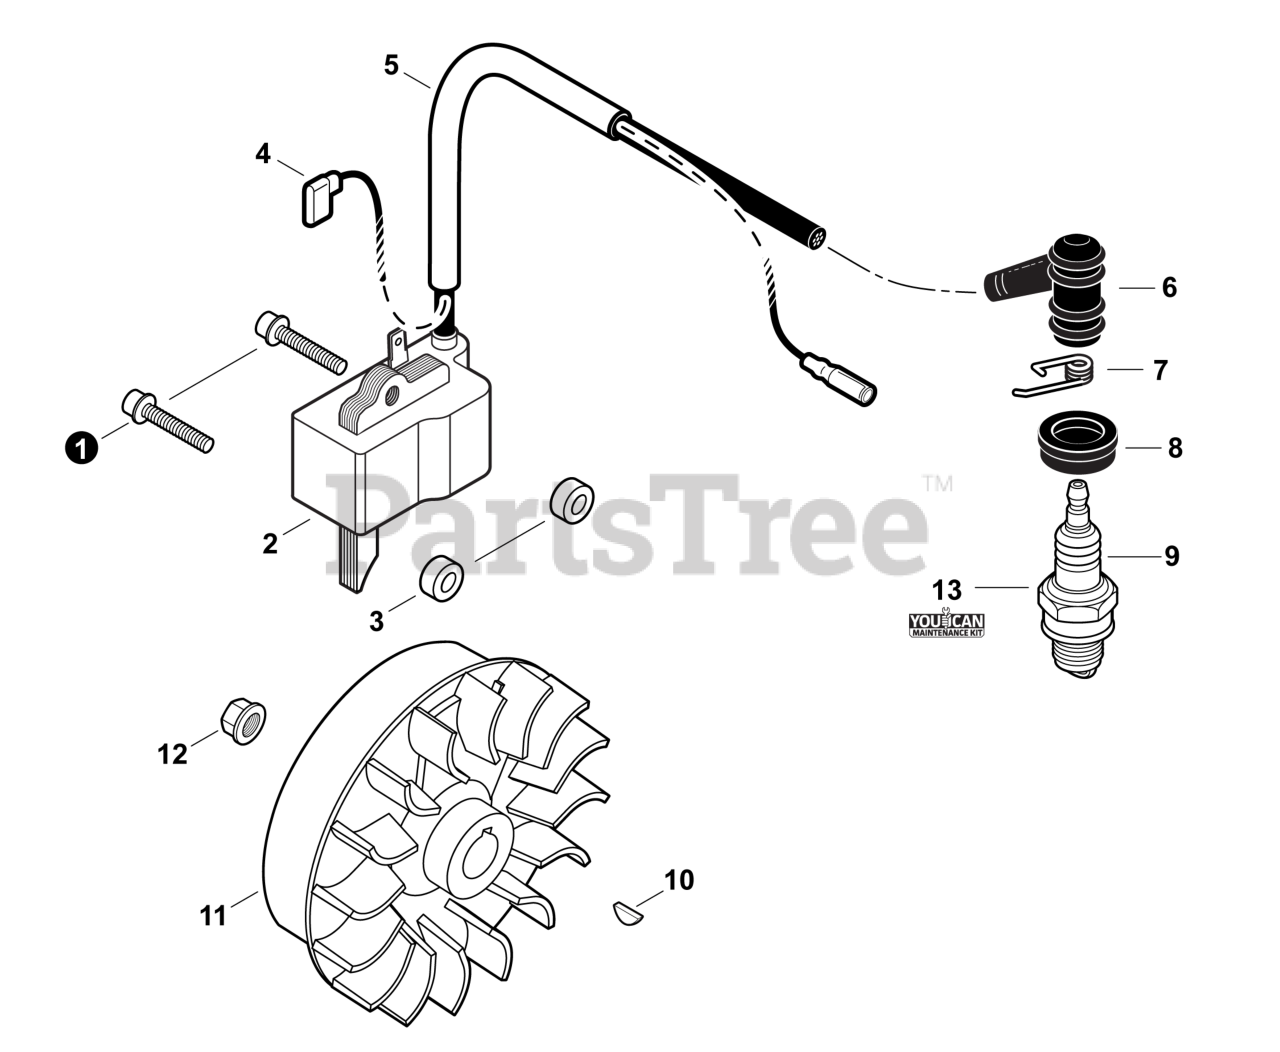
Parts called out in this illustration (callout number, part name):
1	BOLT, ADHESIVE M4×20
2	COIL, IGNITION
3	INSULATOR 4.2×11×6
4	LEAD - IGNITION L= 215
5	TUBE, IGNITION COIL Ø8×L125
6	CAP, SPARK PLUG
7	TERMINAL, SPARK PLUG
8	SEAL, SPARK PLUG
9	SPARK PLUG - BPMR6A
10	KEY, WOODRUFF 3×10
11	FLYWHEEL
13	TUNE-UP KIT - YOUCANT
